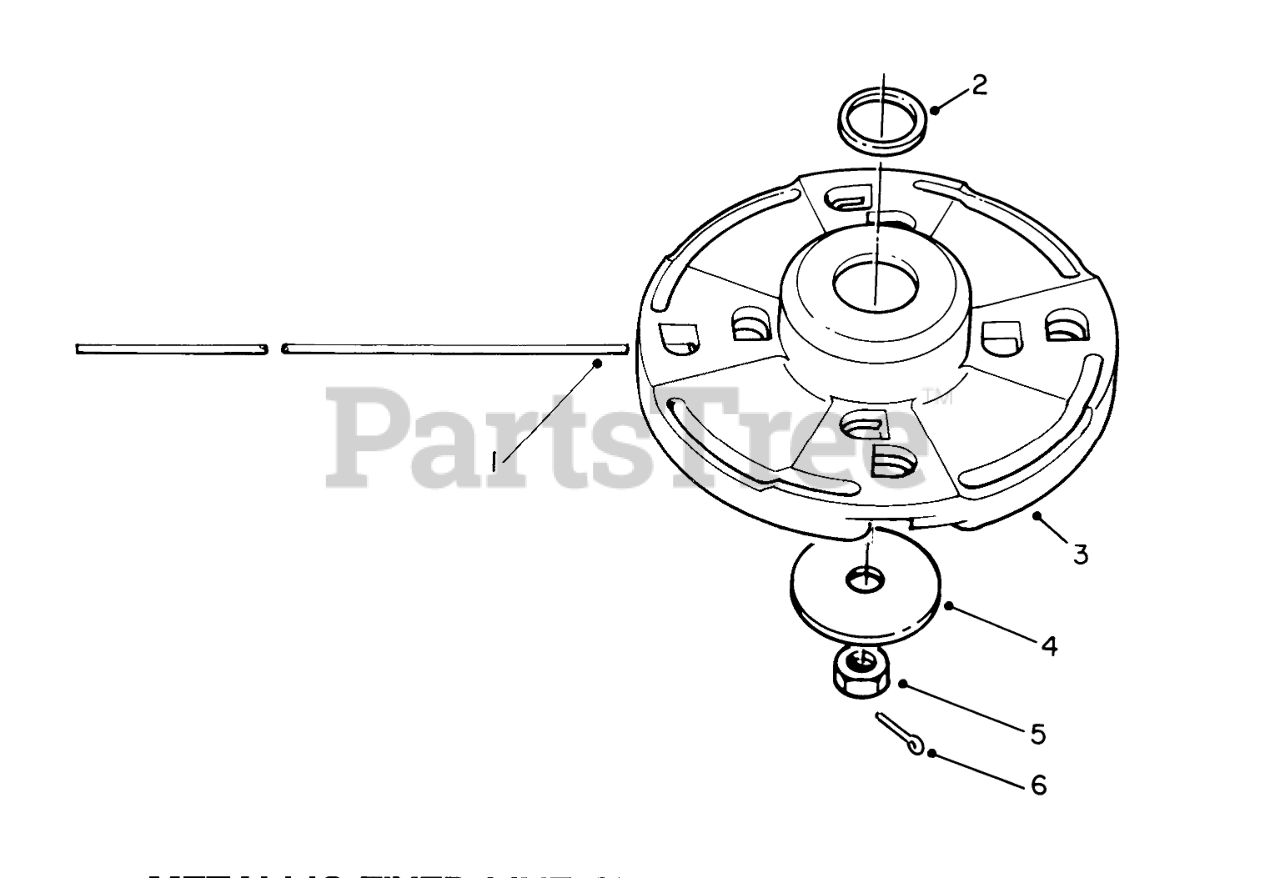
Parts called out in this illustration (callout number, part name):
1	Line-Cutting .105 Dia.
2	SPACER
3	Cutter Head Assembly (Incl. Ref. #2)
4	WASHER
6	1/16 X 1 LG COTTER PIN
